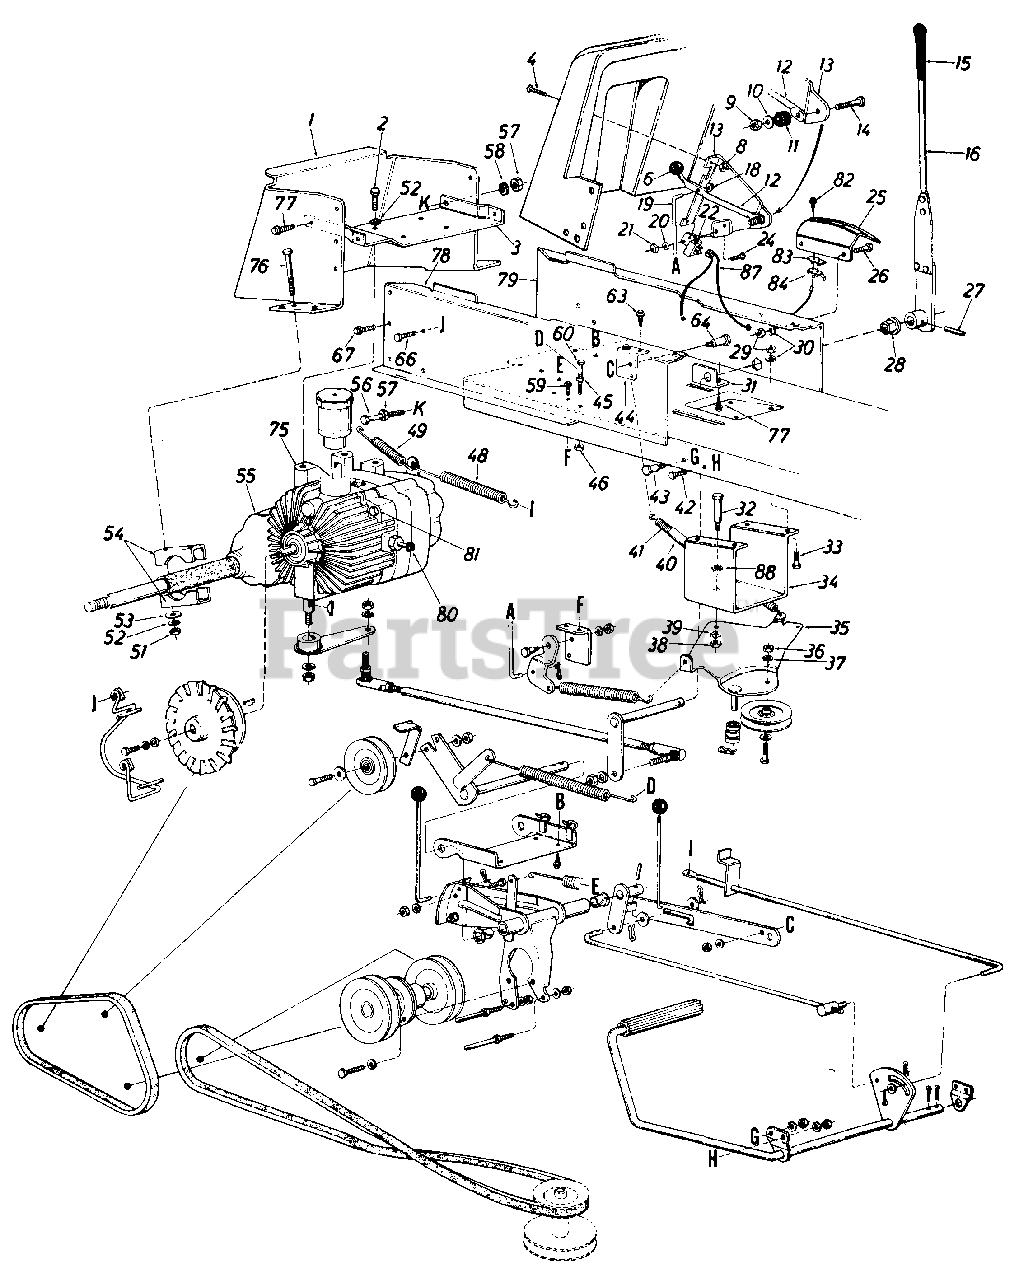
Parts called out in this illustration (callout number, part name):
1	Hitch Plate
2	Hex Bolt 3/8-16 x .75" Lg.
3	Rear Axle Support Brk't.
4	Truss Mach. Scr. 1/4-20 x .50" Lg.
6	Knob Blade Clutch
8	Hex Sems Nut 1/4-20 Thd.
9	Hex Cent. L-Nut 1/4-20 Thd.
10	Fl-Wash. .28" I.D. x .74" O.D. x .063
11	RubberWash. .33" I.D. x .87" O.D. x .30
12	Blade Clutch Lever
13	Deck Clutch Cont. Brk't.
14	Hex Bolt 1/4-20 x 1.00" Lg.
16	Control Arm Ass'y.
18	Push Nut 1/4" O.D. Rod
19	Deck Control Rod
20	Ext. L-Wash. #10 Scr.
21	Hex Nut #10-24 Thd.
22	Saf ety Sw i tc h
24	Truss Mach. Scr. #10-24 x .50" Lg.
25	Speed Control Bracket
26	Hex Bolt 5/16-18 x .62" Lg.
27	Spring Pin Spiral 1/4" Dia. x 1.5" Lg.
28	Hex Flange Brg.
29	Hex Nut 5/16-18 Thd.
30	L-Wash. 5/16" I.D.
31	Speed Control Shaft Brk't.
32	Shld. Scr. .437" Dia. x .162" Lg.
33	Hex Bolt 5/16-18 x 1.00" Lg.
34	Idler Support Brk't.
35	Idler Brk't. Ass'y.
36	Hex Nut 3/8-16 Thd.
37	Belleville Washer 3/8" I.D.
38	Hex Nut 5/16-18 Thd.
39	L-Wash. 5/16" I.D.
40	Convoluted Conduit .50" I.D.
41	Ext. Spring .50" O.D. x 6.37" Lg.
42	Hex Bolt 3/8-16 x .62" Lg.
43	Shld. Scr. .50" Dia. x .395" Lg. (3/8-16)
44	Parking Brake Cam Mtg. Brk't.
45	Hex Nut 5/16-28 Thd.
46	Hex Nut 5/16-18 Thd.
48	Brake Tension Spring
49	Ext. Spring Brake Return
51	Hex Nut 3/8-16 Thd.
52	L-Wash. 3/8 I.D.
53	Fl-Wash. .390" I.D. x 1.00" O.D. x .125" Thk.
54	Rear Axle Bracket
55	Transaxle
56	Hex Bolt 1/4-20 x 2" Lg.*
57	Hex Nut 1/4-20 Thd.
58	L-Wash. 1/4" I.D.
59	Hex Wash. Hd. Self-Tap Scr. 1/4-20 x .50" Lg.
60	Hex Bolt 5/16-18 x 1.50" Lg.
63	Hex Wash. Hd. Self-Tap Scr. 1/4-20 x .50" Lg.
64	Shld. Scr. .437" Dia. x .162" Lg.
66	Hex Wash. Hd. Scr. 3/8-16 x .50" Lg.
67	Hex Wash. Hd. Self-Tap Scr. 5/16-24 x .50" Lg.
75	Hydrostatic Pump Comp.
76	Hex Bolt 3/8-16 x 3.5" Lg.
77	Hex AB-Tap Scr. 5/16 x .75" Lg.
78	Side Panel Upper Frame R.H.
79	Side Panel Upper Frame L.H.
81	Socket Hd. Bolt 3/8-16 x 2.75" Lg.
82	Hex Wash. Hd. Scr. #8 x .50" Lg.
83	Insulator Nut Plate
84	Spring Switch
87	Part of Wire Harness
88	Wave Washer
